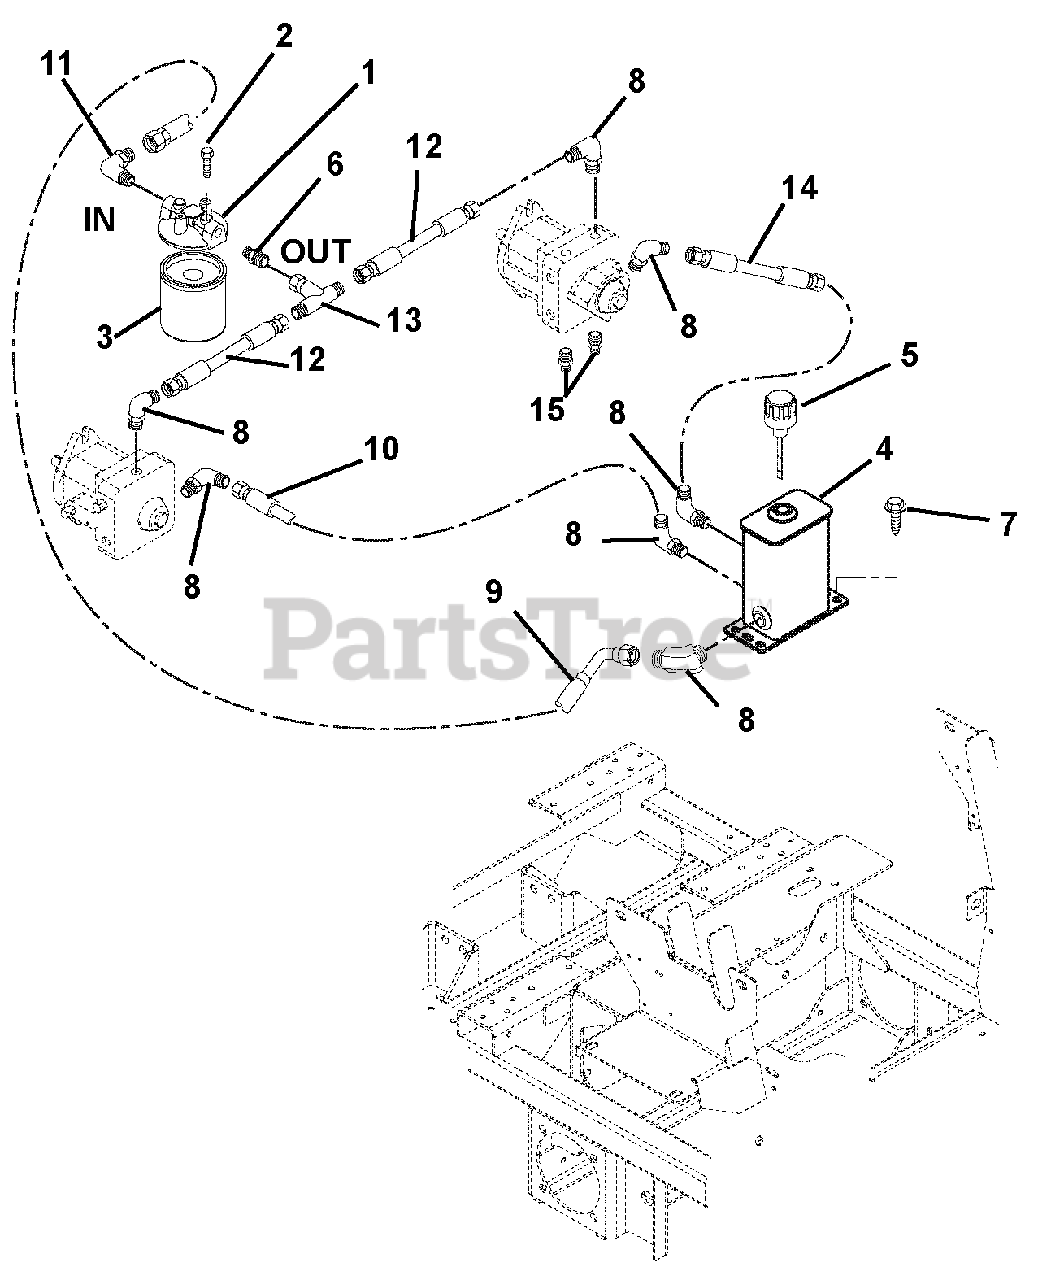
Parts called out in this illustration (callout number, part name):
1	HEAD, FILTER
2	BLT-HEX .25-20X.50 GR5 EPOXY
3	FILTER,OIL-W/BYPASS
4	WMT,FORMED HYD.TANK-3 PORT
5	BREATHER, DIPSTICK
6	ADPTR,FACE SEAL 8X8 1/2 O-RING
7	@SCR-TAP .38-16X.75 HWH TR YWZ
8	FTG. HYD. 90 EL M8F-M8O
9	HOSE, HYD. .50-19-0K F8F0-F8F9
10	HOSE,HYD..50-10-0K FO8J0-FO8JO
11	FTG. HYD. 90 EL M8F-M8O
12	HOSE,HYD. .50-5-0K FO8J0-FO8J0
13	FTG.HYD TEE M8O-F8O-F8O
14	HOSE,HYD..50-16-0K FO8J0-FO8J0
15	FITTING, HYD (4 F5OLO)
